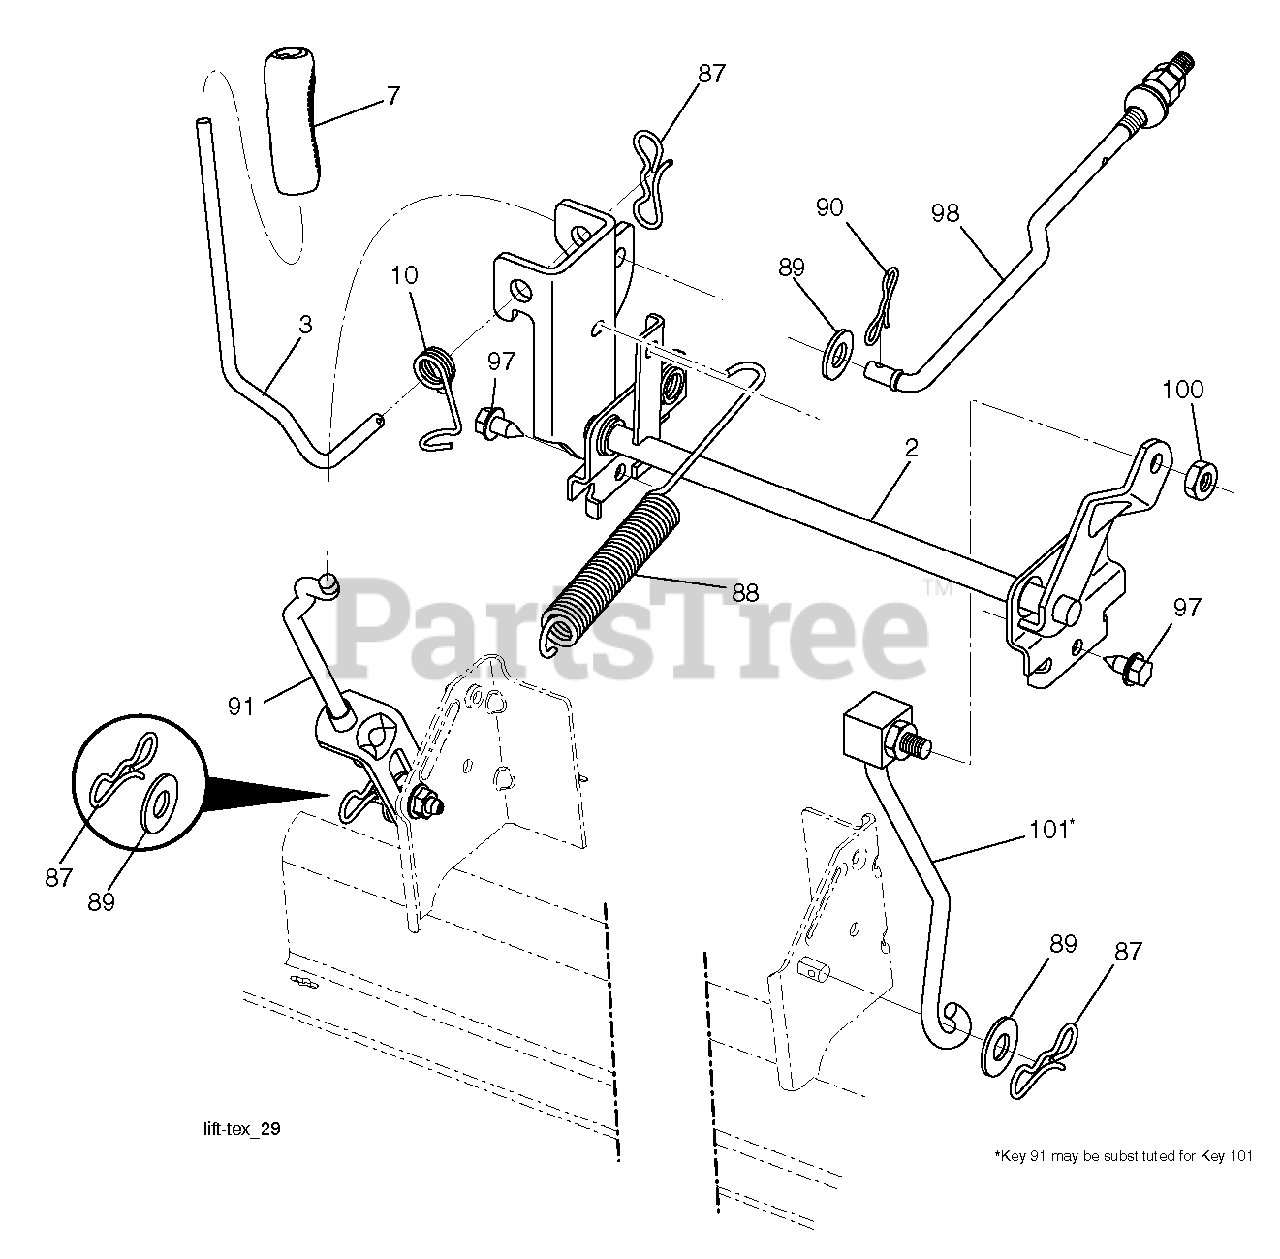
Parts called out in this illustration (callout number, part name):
2	SHAFT.ASM.CROSS.LIFT
3	LEVER.LIFT.HANDLE.LT
7	GRIP.HANDLE.LIFT.PVC.BLACK
10	SPRING.TORSION.LIFT.HANDLE
87	PIN.COTTER.7/16.BOW TI.
88	SPRING.LIFT.ASSIST
89	WASHER.CLEAR.ZINC
90	PIN.COTTER.5/16.BOW TI
91	LINK.ASM.LIFT.REAR
97	SCREW, 3/8-16X3/4
98	LINK.ASM.SUSP.FRONT.MW
100	LOCKNUT
101	LINK.ASM.LIFT.FIXE.38/42/46"
